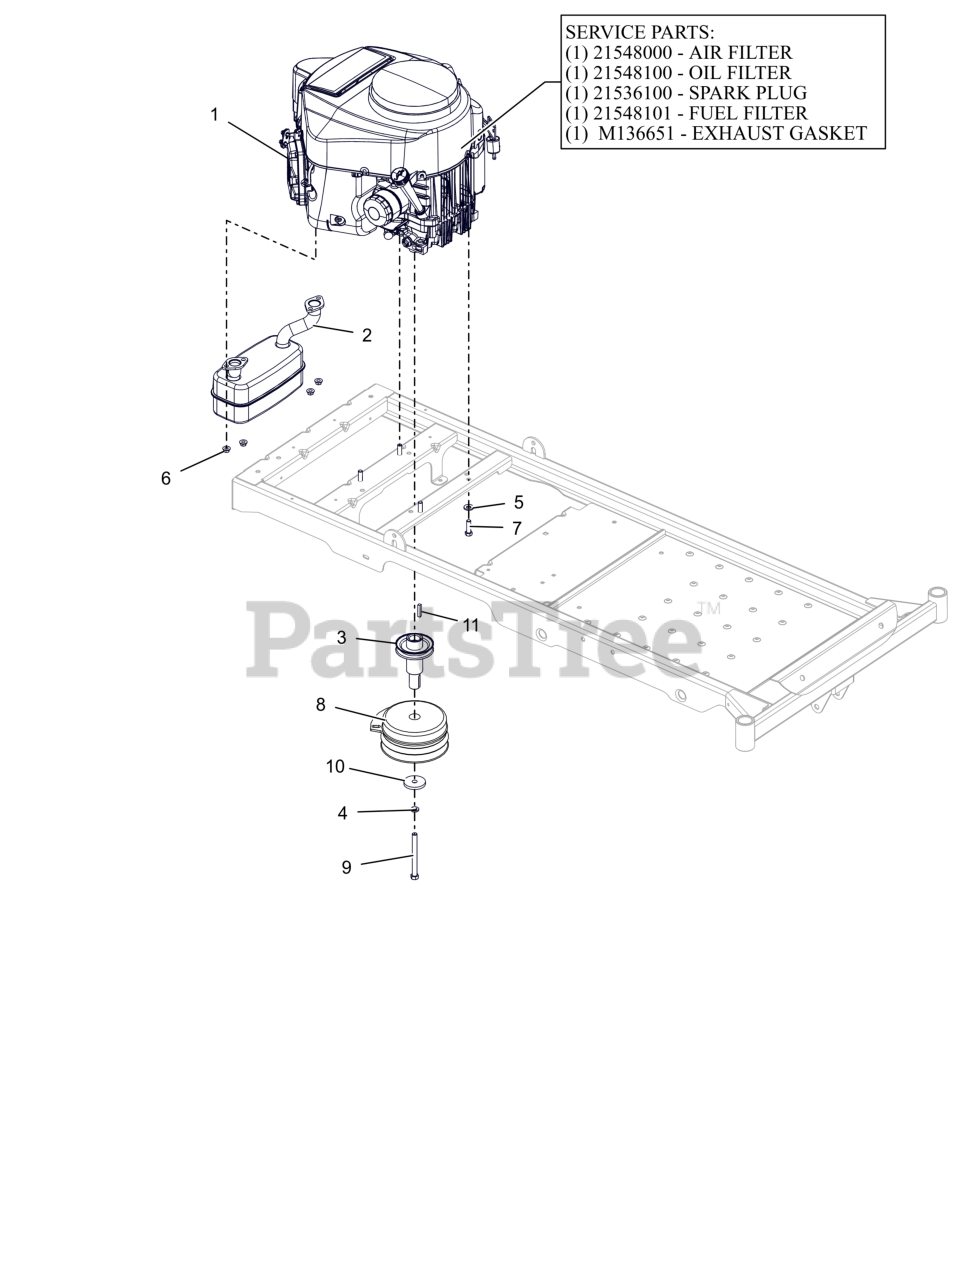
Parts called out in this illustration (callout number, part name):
1	ENGINE, KAWASAKI FR651V
1	AIR FILTER, KAWASAKI FR
1	OIL FILTER, KAWASAKI FR
1	PLUG, SPARK
1	FUEL FILTER-KAWASAKI FR
1	GASKET, MUFFLER #
2	MUFFLER, KAWI TWIN
3	WLDMT, CRANKSHAFT EXTENSION
4	WSHR, LK-REG .438X.109 ZCC
5	WASHER, 3/8" SPRING DISC
6	NUT-LK-TOP-FLG M8 ZCC
7	BLT, HEX .38-16X1.25 G5 ZCC NT
8	CLUTCH, 105 FT*LB MONO POLE
9	BLT, HEX .44-20X4.50 G8 ZCC NT
10	WSHR, FLT .469X2.00X.250 ZCC
11	KEY-SQ .25 X 1.25 X .25 SAE
